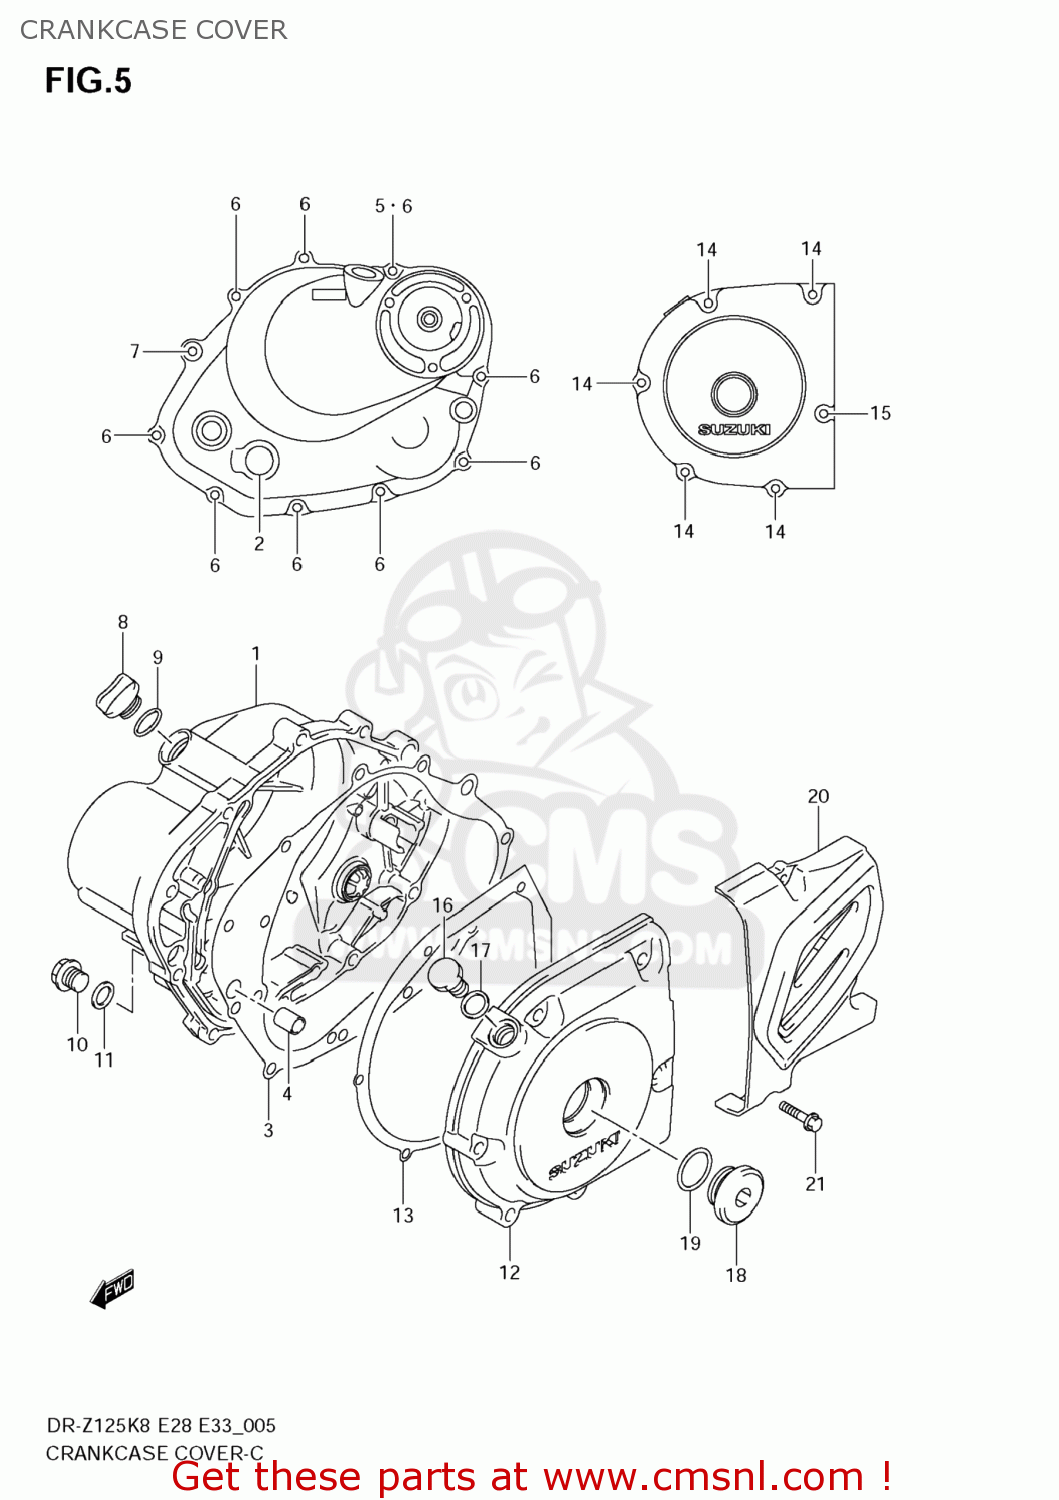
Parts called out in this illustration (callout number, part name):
1	COVER,CLUTCH
2	LENS,OIL LEVEL CHECK
3	GASKET,CLUTCH COVER (NAS)
4	PIN
5	GASKET(5.8X13X1.2) (NAS)
6	BOLT
7	BOLT
8	PLUG,ENGINE OIL FILLER
9	O RING(D:3.1,ID:16.8)
10	PLUG(14X12)
11	GASKET(13.8X18.8X4.8) (NAS)
12	COVER,MAGNETO
13	GASKET,MAGNETO COVER (NAS)
14	BOLT
15	BOLT
16	PLUG(12X9)
17	GASKET(12.1X16.2X3.7) (NAS)
18	PLUG(26X9)
19	O RING(D:3.1,ID:22.7)
20	COVER,ENGINE SPROCKET
21	BOLT
